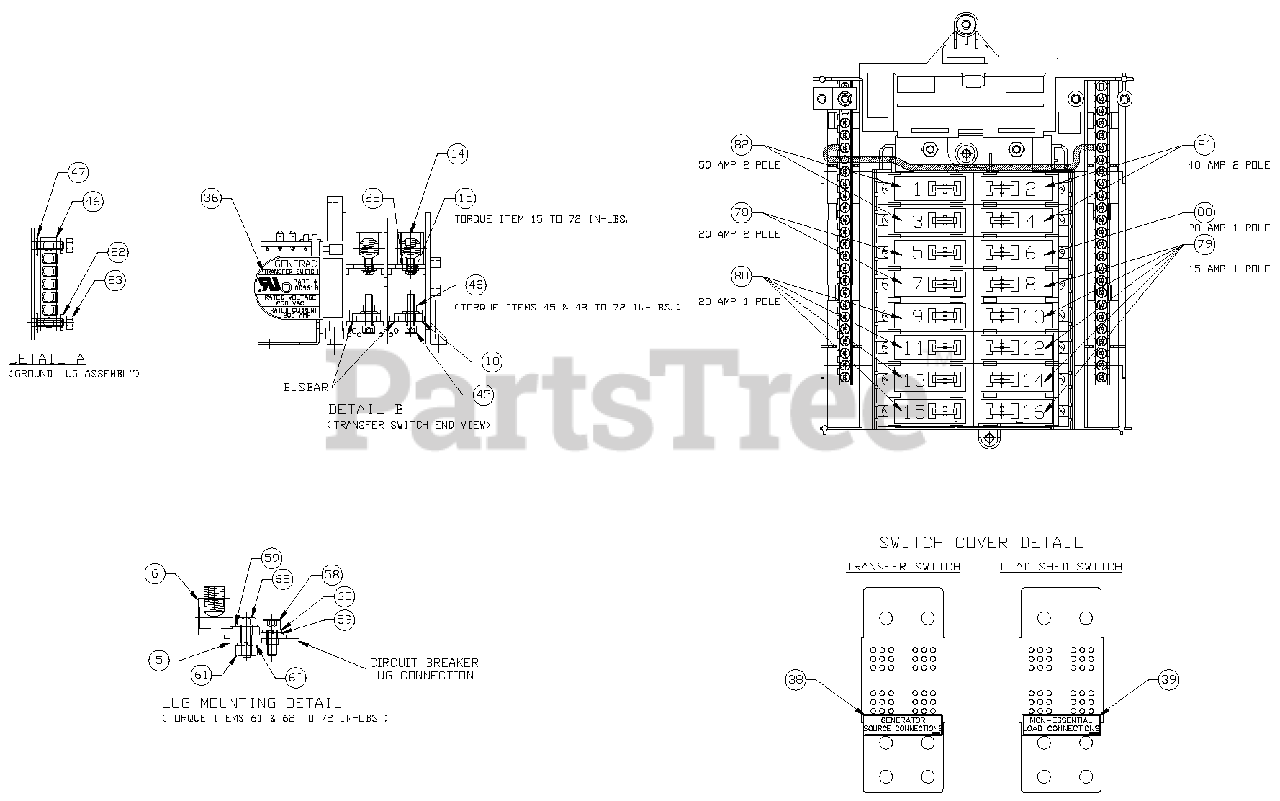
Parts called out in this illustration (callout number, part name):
5	BUSBAR, 200A LUG ADAPTER
6	LUG 300 MCM-6STR
10	BUSBAR, 200A TRANSFER SW T2
14	LUG SOLDERLESS 250-# 6 AL/CU
15	SCREW BHSC 1/4-20 X 3/8
22	WASHER LOCK M6-1/4
23	NUT HEX 1/4-20 SS
36	DECAL, TRANSFER SWITCH INFO
38	DECAL, GENERATOR SOURCE CONNECTION
39	DECAL, NON-ESSENTIAL LOAD CONN
45	SCREW BHSC 1/4-20 X 3/4
46	GROUND BAR (5) 2-14 AWG CONN
47	WASHER SHAKEPROOF EXT 1/4 STL
48	NUT HEX FL WHIZ 1/4-20
58	SCREW SHC M8-1.25 X 20 G8
59	WASHER FLAT 5/16-M8 ZINC
60	WASHER LOCK M8-5/16
61	NUT HEX M8-1.25 G8 CLEAR
62	SCREW HHC M8-1.25 X 25 C8.8
78	CB 0020A 2P PLUG IN
79	CB 0015A 1P PLUG IN
80	CB 0020A 1P PLUG IN
81	CB 0040A 2P PLUG IN
82	CB 0050A 2P PLUG IN
